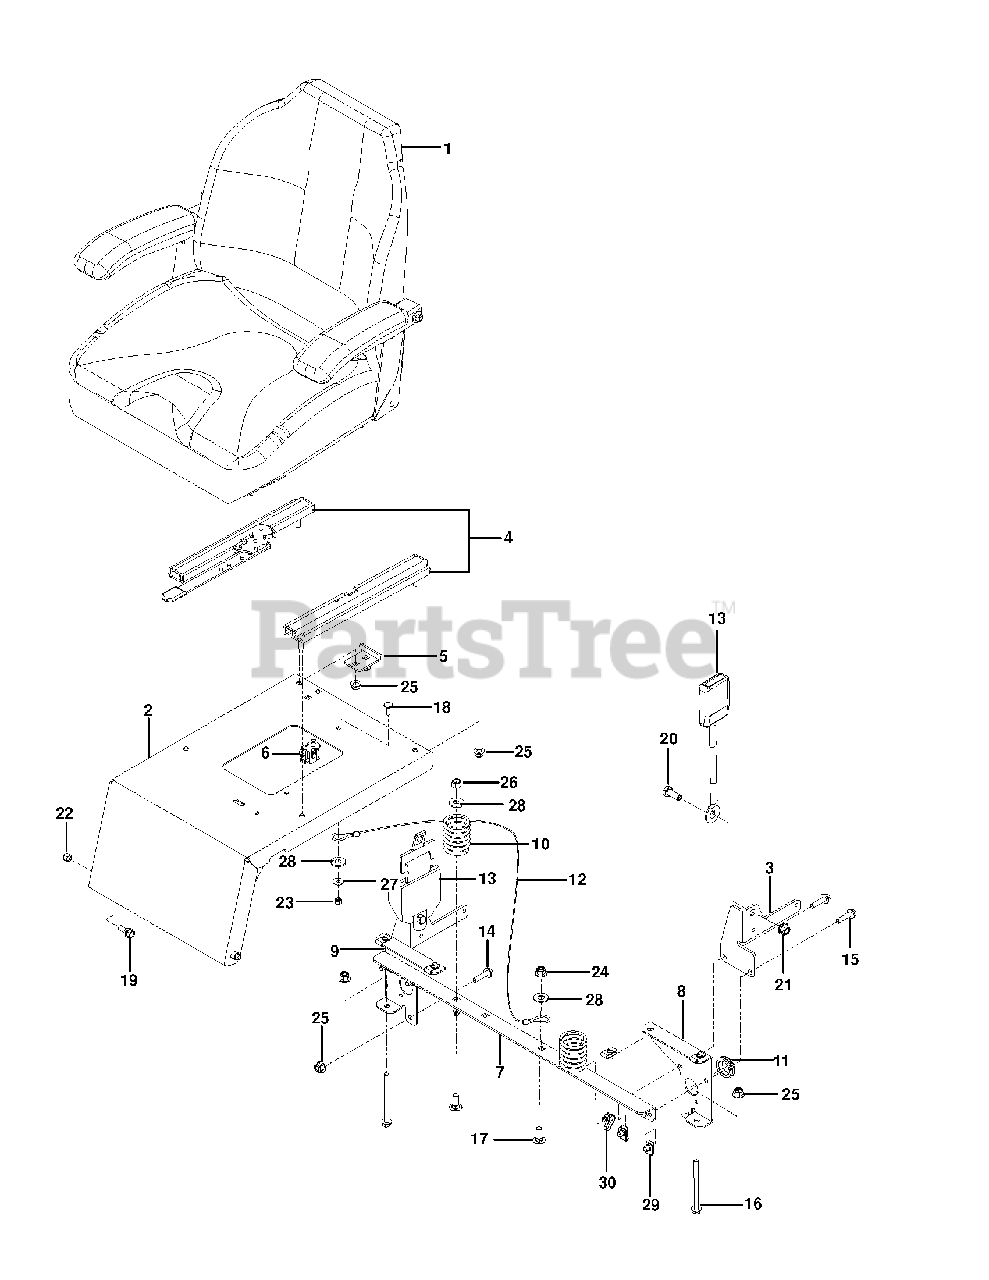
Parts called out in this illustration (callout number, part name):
1	SEAT.907.VINYL.HUSQVARNA
2	KIT.SEAT.MOUNT.W/DECAL
3	MOUNT, SEAT BELT, BLACK
4	4"SINGLE LOCK TRACK SET W/HDWR
5	STOP, SEAT - BLACK
6	SEAT SWITCH
7	SUPPORT, SEAT
8	SUPPORT, RT, BLK
9	SUPPORT, LT, BLK
10	SPRING COMPRESSION
11	RUBBER GROMMET
12	SEAT LANYARD
13	Seat Belt, Retractable
14	HHFS 5/16-18 X 3/4
15	HHFS 5/16-18 X 1.25 TPBLT GD 5
16	HHFS 5/16-18 X 3 3/4
17	RHSNB 3/8C X 1
18	RHSNB 1/4C X 3/4
19	SB 5/16-18 HEX HD GD5, BLK ZN
20	SCREW 7/16-20 X 1 HHB GR5
21	NUT HEX 7/16F LOCK RP
22	NUT 5/16 NYLOC
23	RP_NUT 1/4-20 NYLOC
24	NUT 3/8-16 HEX FLG NYLOC ZD
25	5/16-18 NYLOC FLANGE NUT
26	NUT 3/8-16 NYLOC
27	WASHER 1/4 FLAT
28	RP WASHER 3/8 FLAT
29	U-CLIP 5/16-18 NUT RETAINER
30	TIE WRAP, 8-3/8", W/CLIP
